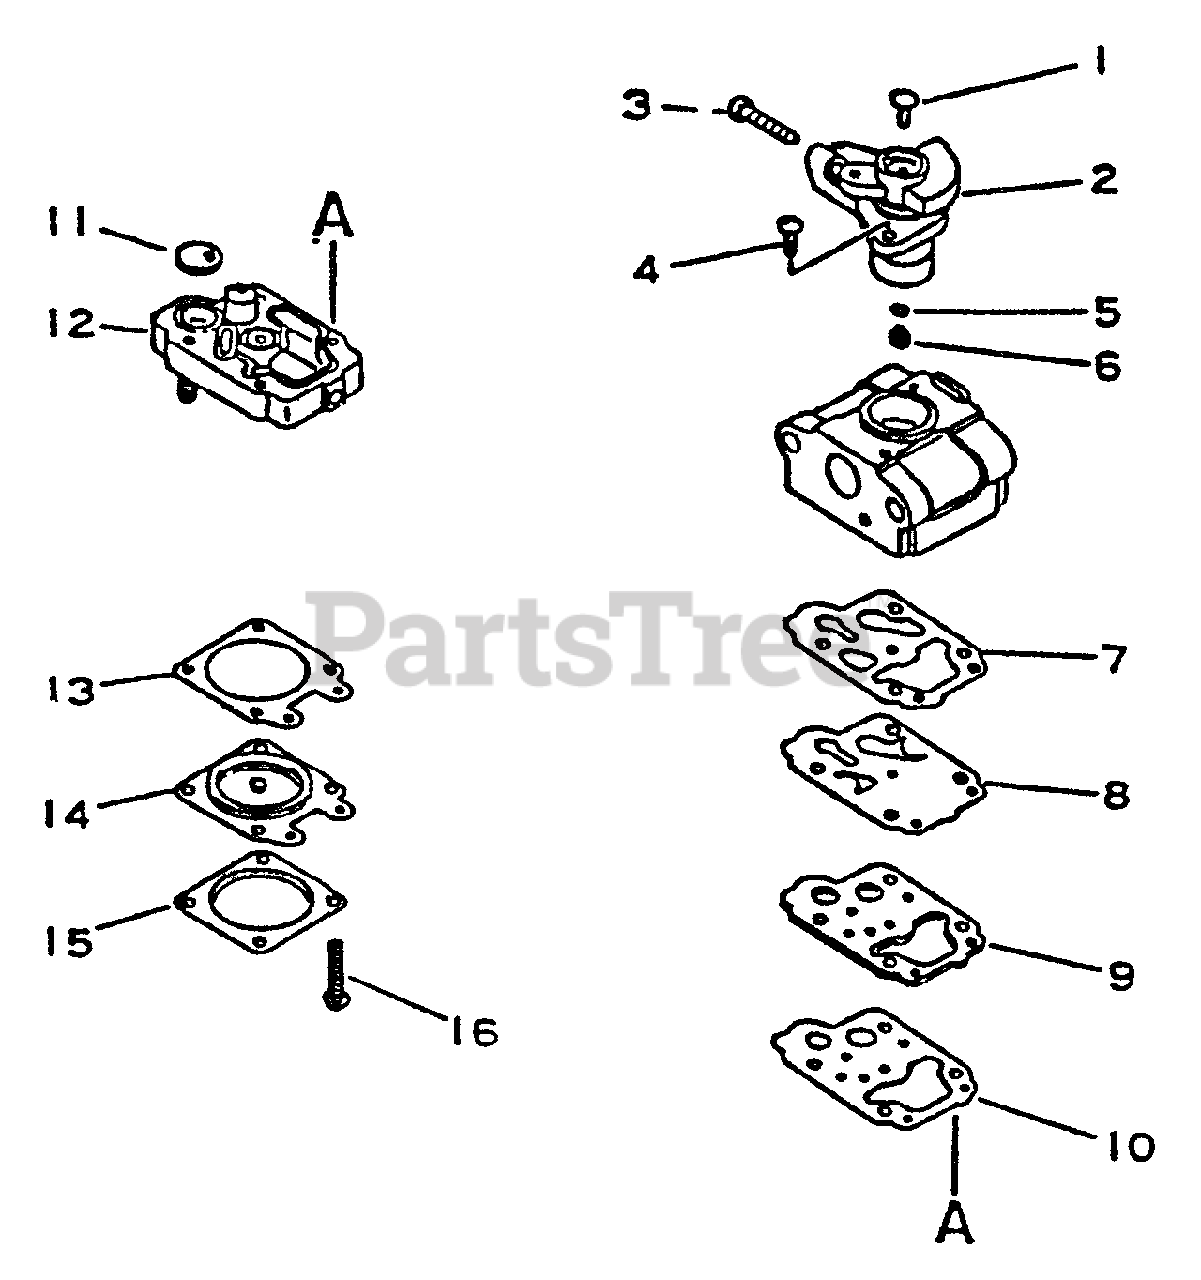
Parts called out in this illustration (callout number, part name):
1	PLUG, WELCH
2	VALVE, THROTTLE
3	SCREW, IDLE ADJUST
5	O-RING
6	JET
7	GASKET, PURGE
8	DIAPHRAGM, PURGE
9	PLATE, PUMP
10	GASKET, PLATE
11	STRAINER
12	BASE, PURGE
13	GASKET, METERING
14	DIAPHRAGM, METERING
15	COVER, METERING
